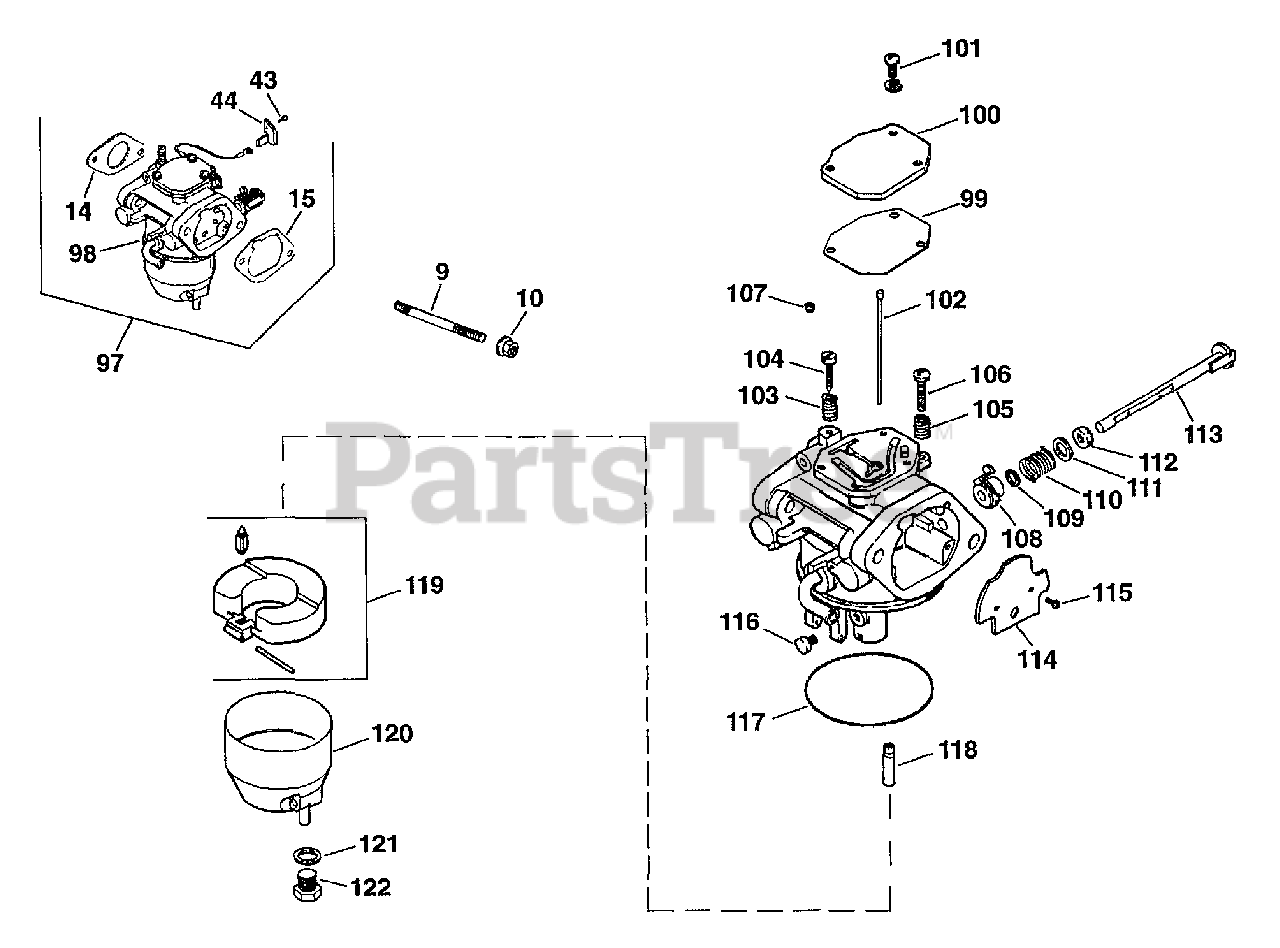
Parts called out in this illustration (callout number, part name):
9	Stud, M6x1.0x105
10	NUT - USE M-641060
14	GASKET, CARBURETOR
15	GASKET, AIR CLEANER BASE
44	Screw, phillips hd. M2x0.45x6
97	KIT, CARBURETOR W/GASKET-NIKF
99	KIT - USE 24 757 20
100	COVER, PASSAGE - DISCONTINUED
101	SCREW DISCONTINUED
102	Jet, slow
103	KIT - USE 24 757 18
104	SCREW, IDLE ADJUST - USE 24 757 18
105	SPRING, THROTTLE - DISC
106	KIT - USE 24 757 18
107	Jet, air bleed
109	RING, CHOKE LEVER-USE 24 757 19-S
111	COLLAR, CHOKE-USE 24 757 19-S
112	WASHER-USE 24 757 19-S
113	SHAFT, CHOKE-USE 24 757 19-S
114	PLATE, CHOKE-USE 24 757 19-S
115	SCREW - DISCONTINUED
116	Jet, main
117	KIT - USE 24 757 20
118	NOZZLE DISCONTINUED
119	KIT - USE 24 757 18
120	CHAMBER, FLOAT
121	DISC. SEE PARTS BULLETIN
122	SCREW, CHAMBER SET - DISC.
